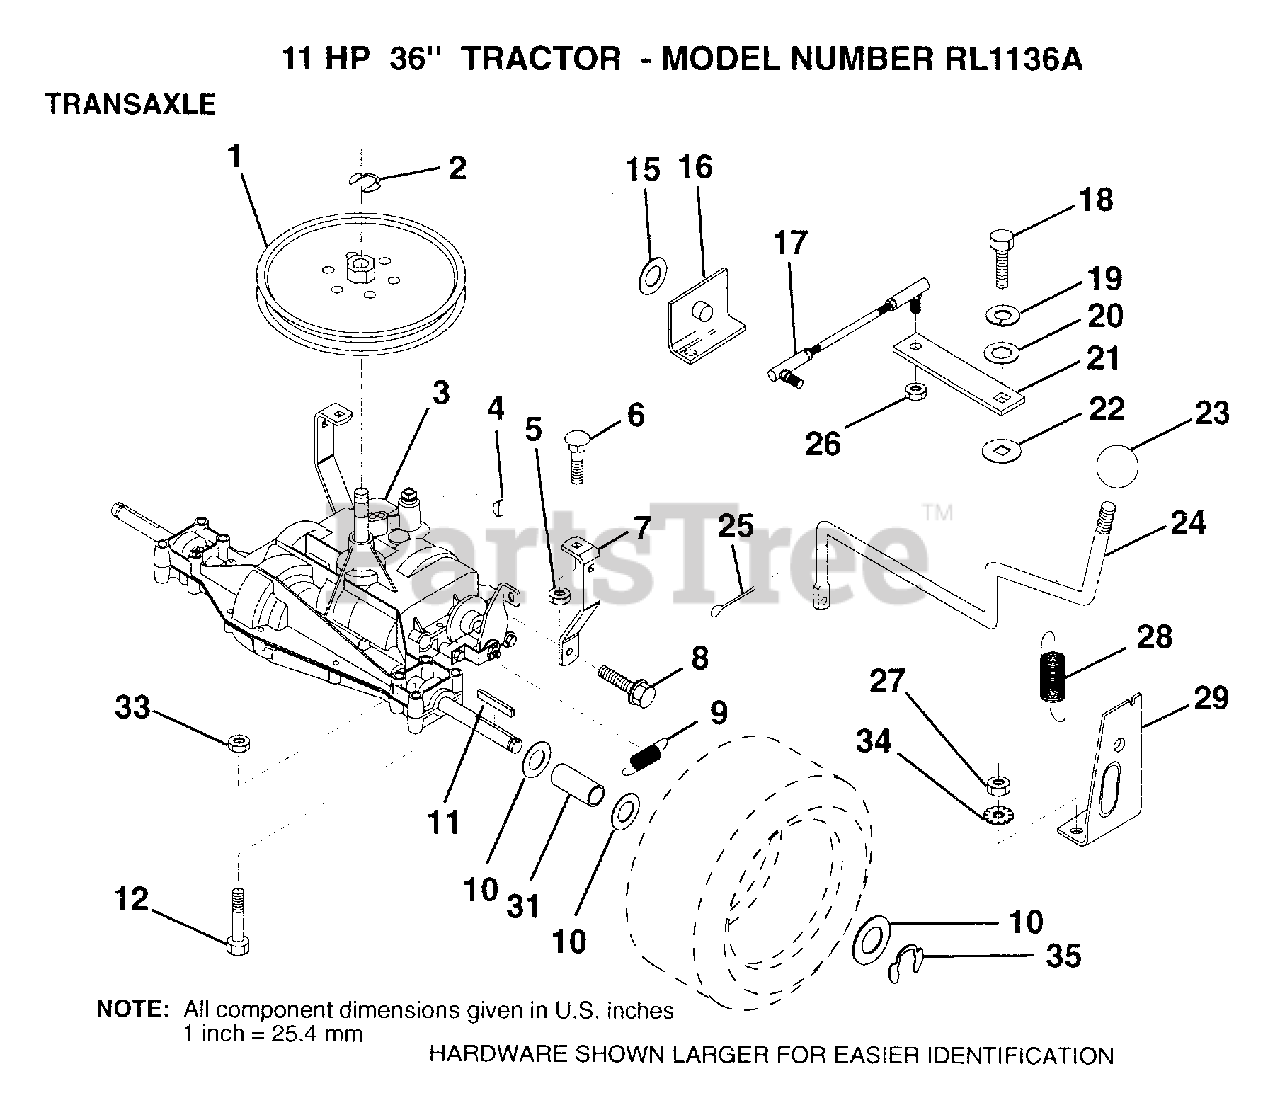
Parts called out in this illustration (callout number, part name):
1	PULLEY
6	BOLT
7	"STRAP,TORQUE"
8	SCREW
10	WASHER
11	SQUARE KEY
12	BOLT
16	"SUPT,HDLE SHT LH"
17	"LINK,SHIFT"
19	LOCKWASHER
20	WASHER LT
21	ARM SHIFT
22	WASH-SHFT PLT LT
23	KNOB T (1/2-HOLE)
24	"ROD,SHIFT"
25	PIN COTTER 1/8
26	NUT.LOCK.5/16-24
28	"SPRING,EXT"
29	"SUPT,HDLE RH"
31	SPACER
34	LOCKWASHER.5/16.E
35	E-RING LT
